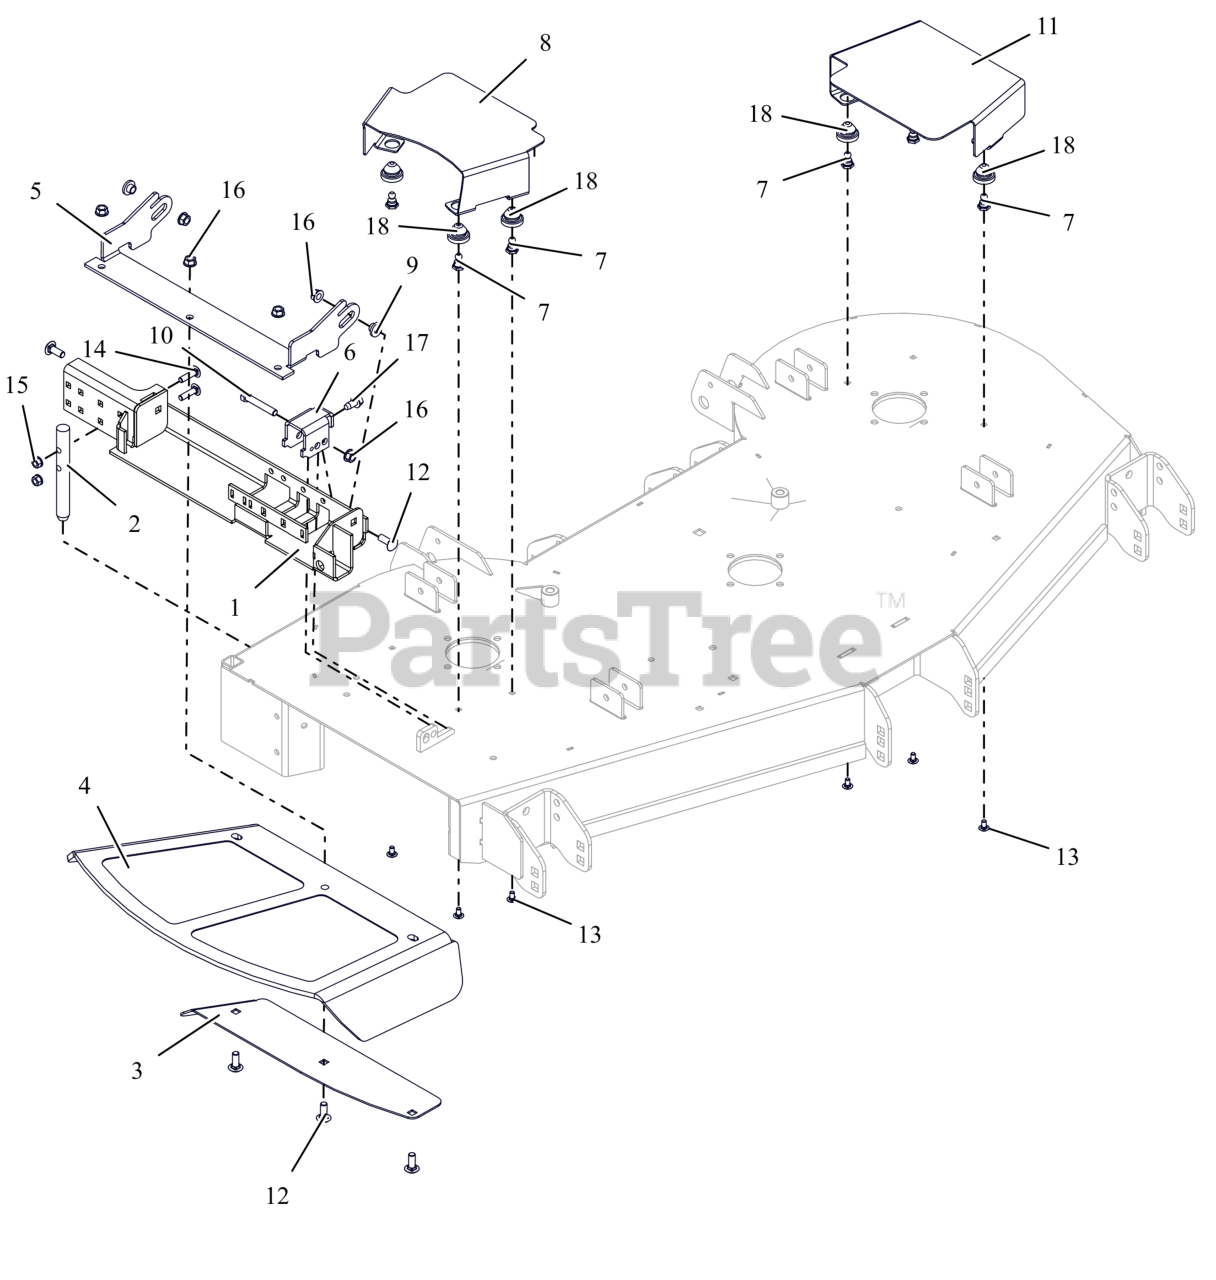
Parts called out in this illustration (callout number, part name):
1	WLDMT, GRASS CATCHER
2	PIN, DISCHARGE CHUTE X-DRILLED
3	48-60 DISCH CHUTE CLMP PLT-BLK
4	CHUTE,48-60" FRMD RUBBER DISCH
5	BRKT, 48-60" CHUTE MTG
6	BRKT, DISCH. CHUTE MTG
7	STUD, BALL FEMALE .250-20 THREAD
8	GUARD, RH DECK BELT (RED)
9	BSHG-FLG .385X.500X.875X.406
10	BLT,HEX .38-16X2.25 G5 ZCC
11	GUARD, LH DECK BELT (RED)
12	BLT,RHSSN .38-16X1.00 G5 ZCC
13	BLT, RHSSN.25-20X.500 G5 ZCC
14	BTL,RHSSN .313-18 X 1.25 G5 ZCC
15	NUT,LK-CTR-FLG .31-18 GF ZCC
16	NUT-LK-CTR-FLG .375-16 GF ZCC
17	SCR,TAP .375-16X.75 HWH TR ZCC
18	COUPLING, RUBBER PUSH-IN
